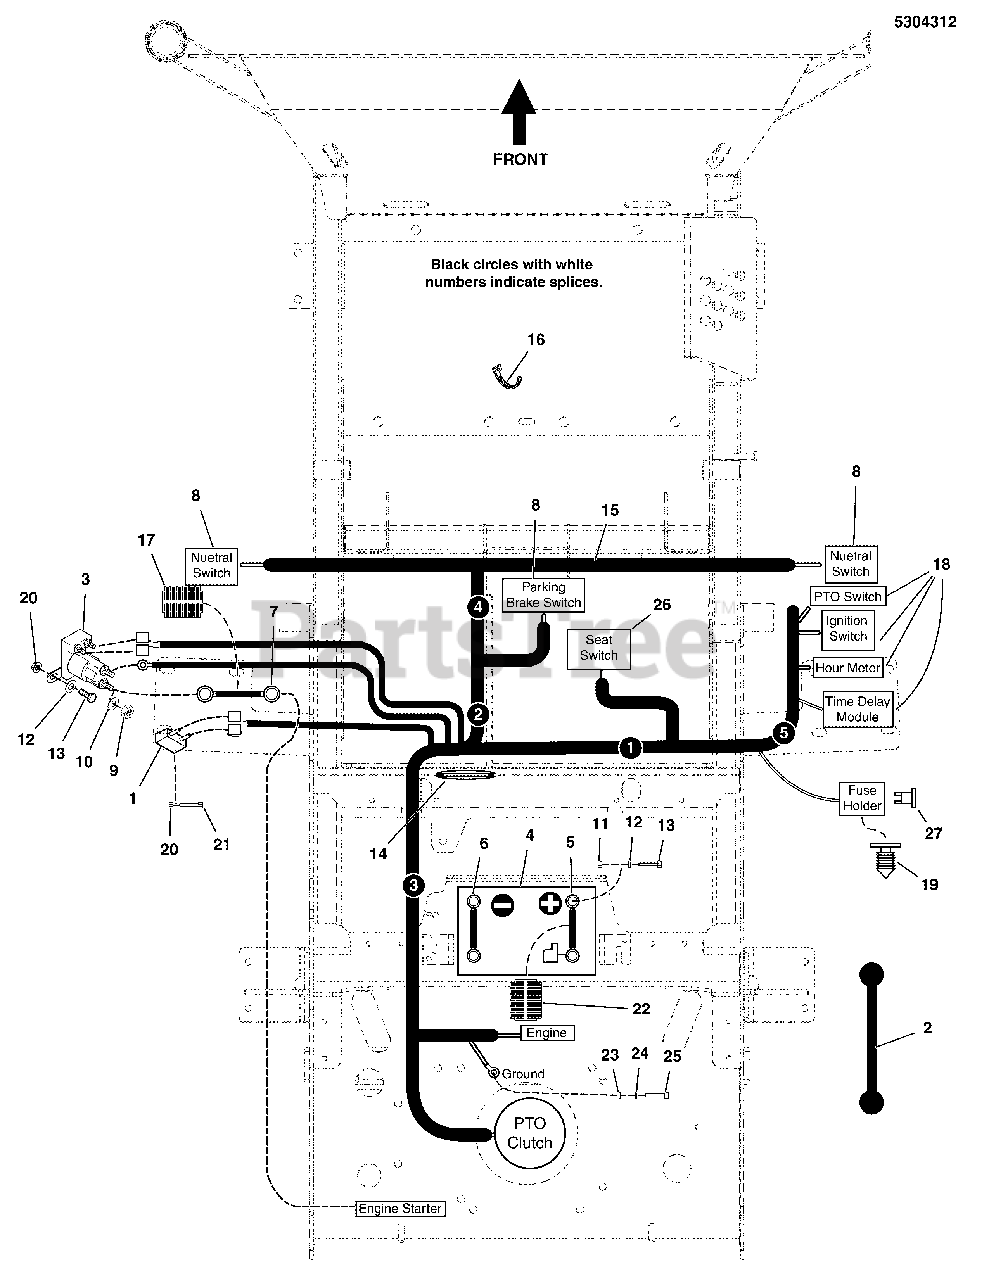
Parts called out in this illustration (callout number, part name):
1	BREAKER-CIRCUIT 12VOLT 20AMPS W/TAB
2	STRAP-BLACK RUBB
3	SOLENOID-4 POLE 12 VOLT DC (TROMBETTA)
4	BATTERY, WET ( BCIU1, 300 CCA)
5	BATTERY CABLE, POS, 15, 1/4-5/16
6	BATTERY CABLE, NEGATIVE, 10"
7	BATTERY CABLE, POS, 22, 1/4-5/16
8	SWITCH, PLUNGER, NO/NC SNAP-IN
9	NUT, 5/16-24 JAM
10	WASHER, 5/16 LIGHT LOCK
11	NUT, 1/4-20 HEX SERR. FLANGE
12	WASHER, 1/4 SAE
13	BOLT, 1/4-20 X 3/4 GD5 YZ
14	GROMMET, 1-1/2" ID FOR 1/4" METAL
15	WIRE HARNESS, CONTENDER
16	TIE, SELF-LOCKING, 12"
17	WIRE LOOM, 3/8 ID X 18 IN
18	SEE INSTRUMENT CONTROL PANEL GROUP
19	FIR TREE MOUNT, PACKARD
20	NUT, 1/4-20 HEX NYLOCK FLANGE
21	SCREW,1/4-20X3/4, ZINC PHOS & OIL
22	WIRE LOOM, 3/8 ID X 12"
23	WASHER, 5/16 INT. TOOTH LOCK
24	WASHER, 5/16 SAE
25	BOLT, M8-1.25 X 20MM GD8.8
26	SWITCH, PLUNGER, NO, SINGLE POLE SNAP-IN
27	FUSE, ATO 15 AMP (SV)
